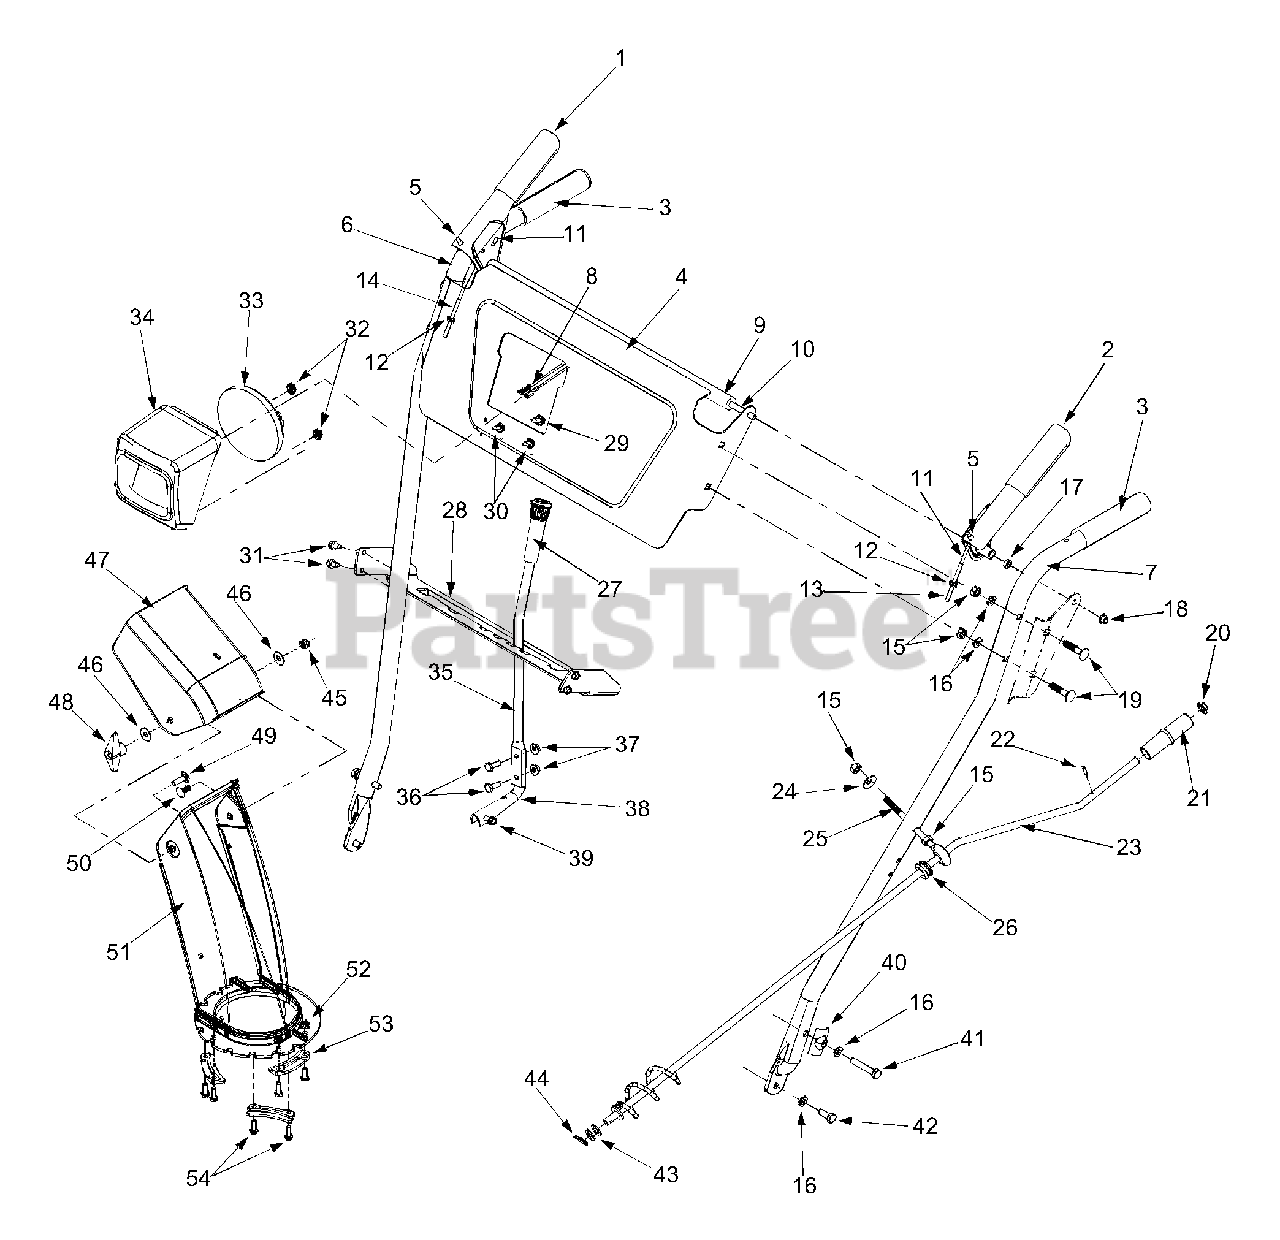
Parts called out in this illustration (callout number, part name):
1	Clutch Lever Assembly - RH
2	Clutch Lever Assembly - LH
5	Bumper Rubber
9	Pivot Rod Cover
10	Pivot Rod
11	"Z" Fitting
12	Hex Jam Nut
13	Auger Clutch Cable
14	Drive Clutch Cable
15	Hex Nut 5/16-18
16	Lock Washer 5/16
17	Spacer
18	Nut Cap
19	Carriage Bolt 5/16-18 x 1.5
20	Push Rod Cap
21	Chute Crank Knob
22	Roll Pin
23	Chute Crank Assembly
24	Bell Washer .340 ID x .873 OD
25	Eyebolt
26	Rubber Grommet
30	Hex Washer Screw #10 16 x .625
31	Hex Washer Screw 1/4-20 x .50
32	Hex Nut
33	Headlight 18 Watt
34	Headlight Cover
36	Hex Cap Screw 1/4-20 x .75
37	Hex Lock Nut 1/4-20
38	Shift Lever Spring
39	Hex Washer
40	Handle Tab
41	Hex Cap Screw 5/16-18 x 1.75
42	Hex Cap Screw 5/16-18 x .75
43	Flat Washer 3/8 ID x .738 OD
44	Cotter Pin
45	Hex Lock Nut 5/16-18
46	Washer 5/16
47	Upper Chute
48	Knob 5/16-18
49	Carriage Screw 5/16-18 x 1.0
50	Carriage Bolt 5/16-18 x .75
51	Lower Chute
52	Hex Lock Nut 1/4-20
53	Chute Flange Keeper
54	Hex Cap Screw 1/4-20 x .75
